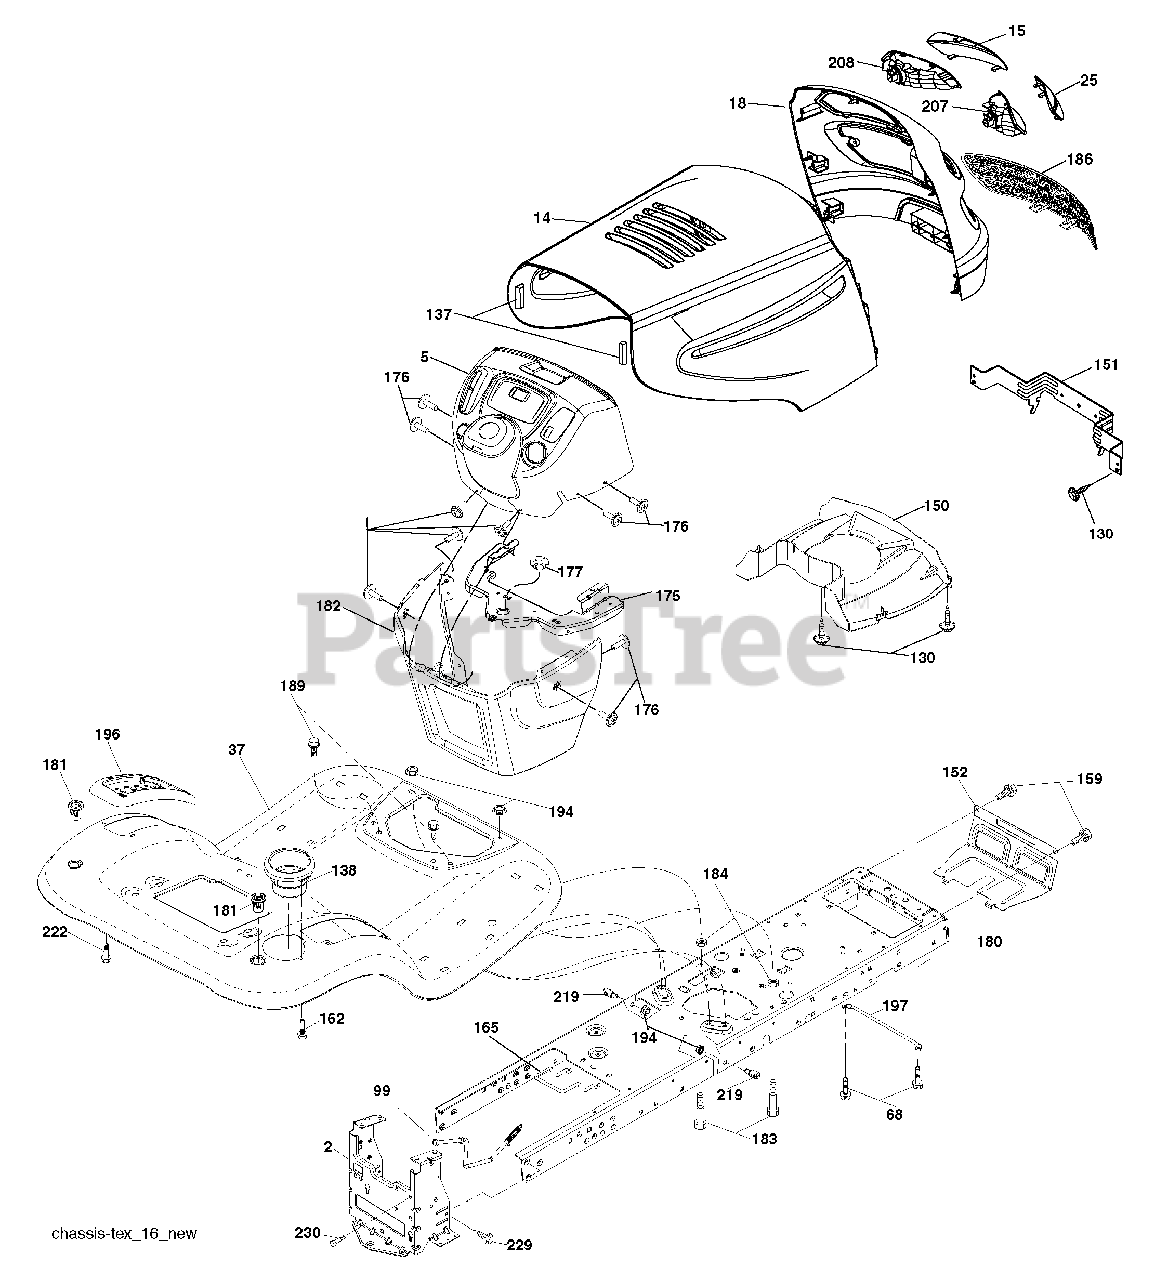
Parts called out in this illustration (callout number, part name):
2	Drawbar
5	Dash
14	Hood
15	Lens Grille LH
18	Grille
25	Lens Grille RH
68	Screw THDROL 5/16-18 x 1/2
99	Rod Bypass Asm
130	Screw 10 x 3/4 Single Lead-Hex
137	Bumper Hood
138	Cupholder
150	Duct Heat Hood
151	Bracket Pivot
152	Shield Browning/Debris
159	Screw Hexwsh Thdrol 3/8-16 x 3/4
162	Screw Hex Wsh Hi-Lo 1/4 x 1/2 unc
165	Bracket Support Tank
175	Crossmember
176	Screw 10-24 x 5/8 Wshd Qdrx
177	Bushing Steering
181	Bushing Mtg. Fender Crgo.
182	Dash Lower
183	Bolt Fin Hex 5/16-18 x 1-1/4
184	Spacer Fender
189	Screw 5/16-18 x 3/4
194	Nut Lock Hex Flange 5/16-18
196	Console Asm. Deck Lift
197	Rod Pivot Chassis
207	Bezel RH
208	Bezel LH
219	Stud Fastener
222	Screw thd Roll 1/4-20 x 5/8
229	Screw 3/8-16 x 1
230	Bolt Shoulder 5/16-18
230	Plug Cruise/Hook/Phone
